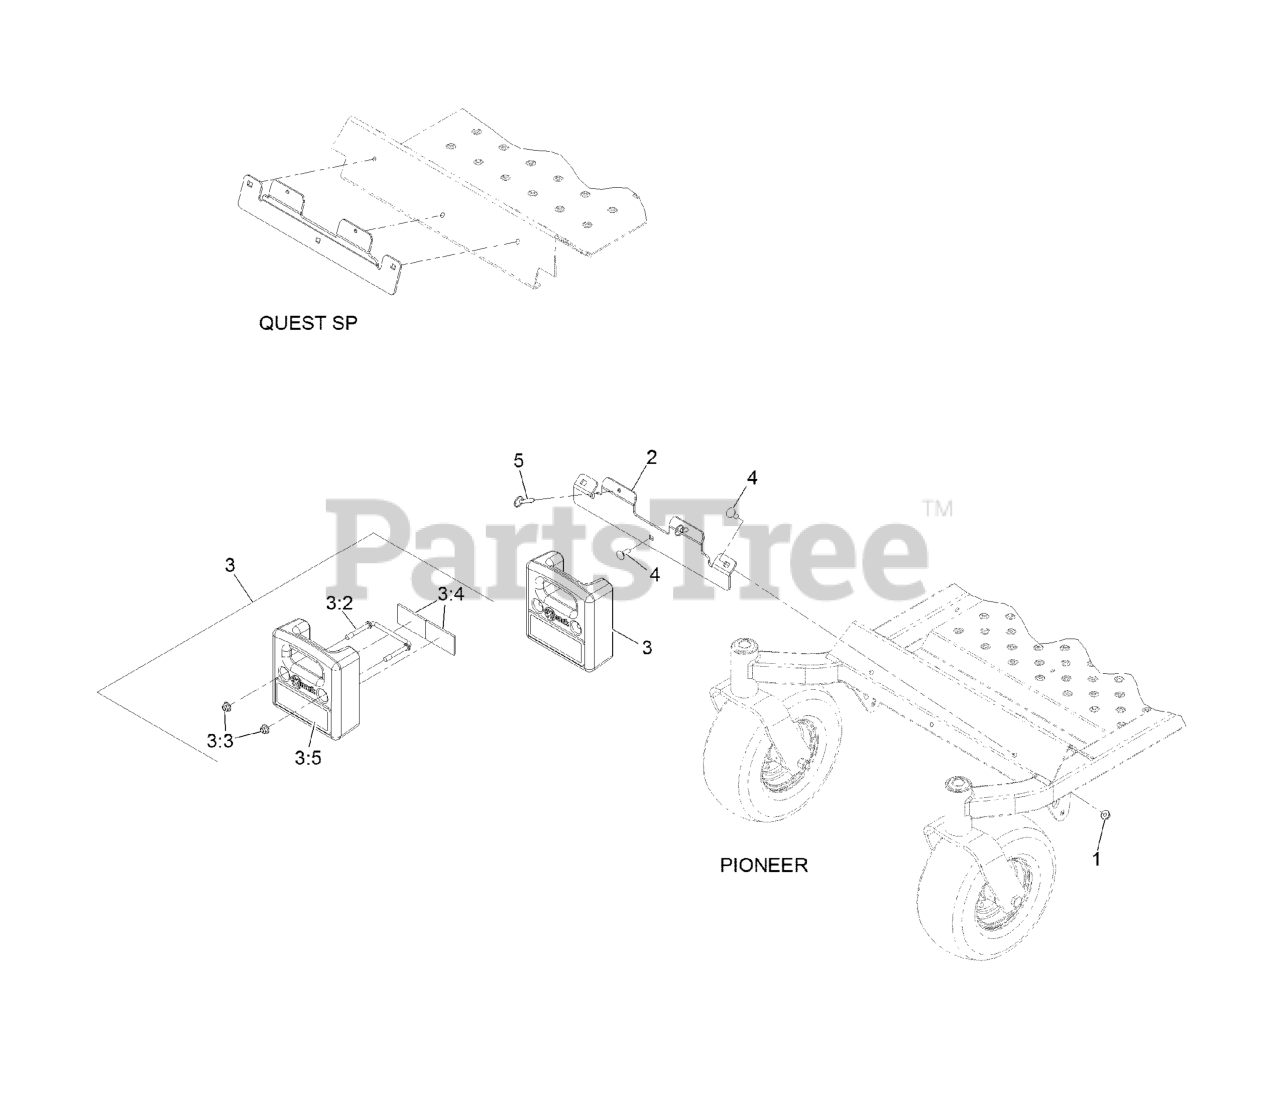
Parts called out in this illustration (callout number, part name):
1	NUT-HF, NI
2	BRACKET-WEIGHT MOUNT
3	WEIGHT ASM
3:2	WIREFORM-WEIGHT
3:3	NUT-HF, NI
3:4	CUSHION-RUBBER
3:5	DECAL-WARNING WEIGHT
4	BOLT-CARR
5	PIN-BALL, DETENT
